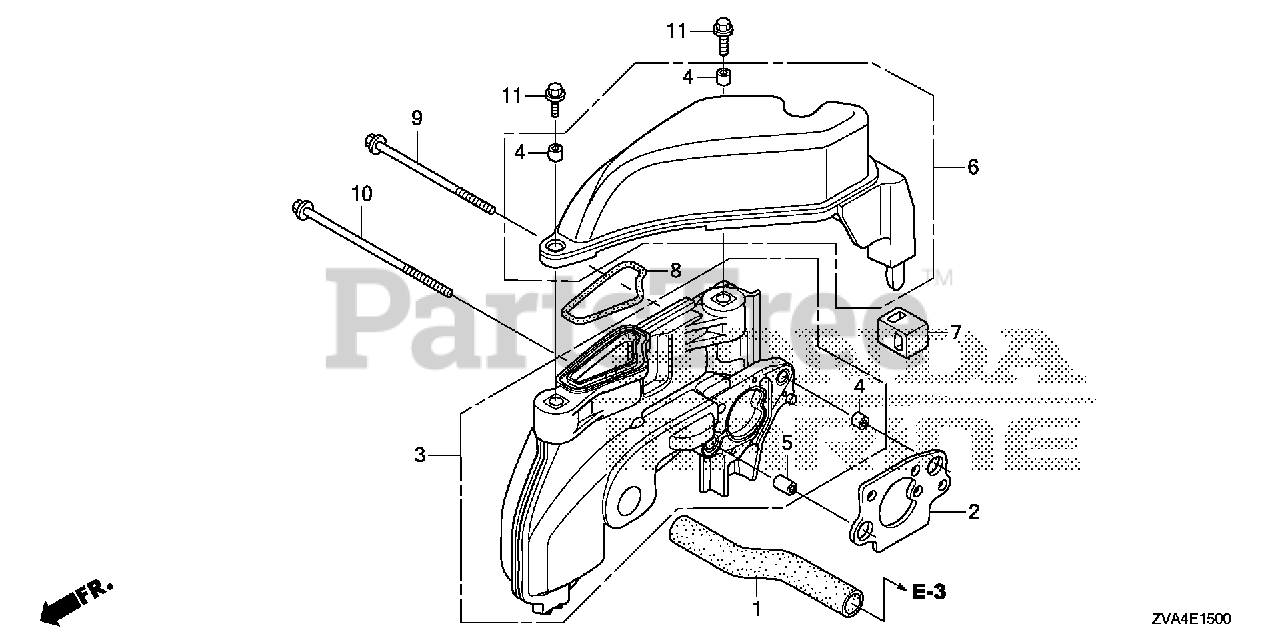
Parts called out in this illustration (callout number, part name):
1	TUBE, BREATHER
2	GASKET, AIR GUIDE
3	GUIDE, AIR INLET
4	COLLAR, DISTANCE
5	COLLAR, DISTANCE (14MM)
6	CASE, MUFFLER
7	GROMMET, MUFFLER
8	SEAL, MUFFLER
9	BOLT, FLANGE (5X62)
10	BOLT, FLANGE (5X70)
11	BOLT, FLANGE (5X12)
